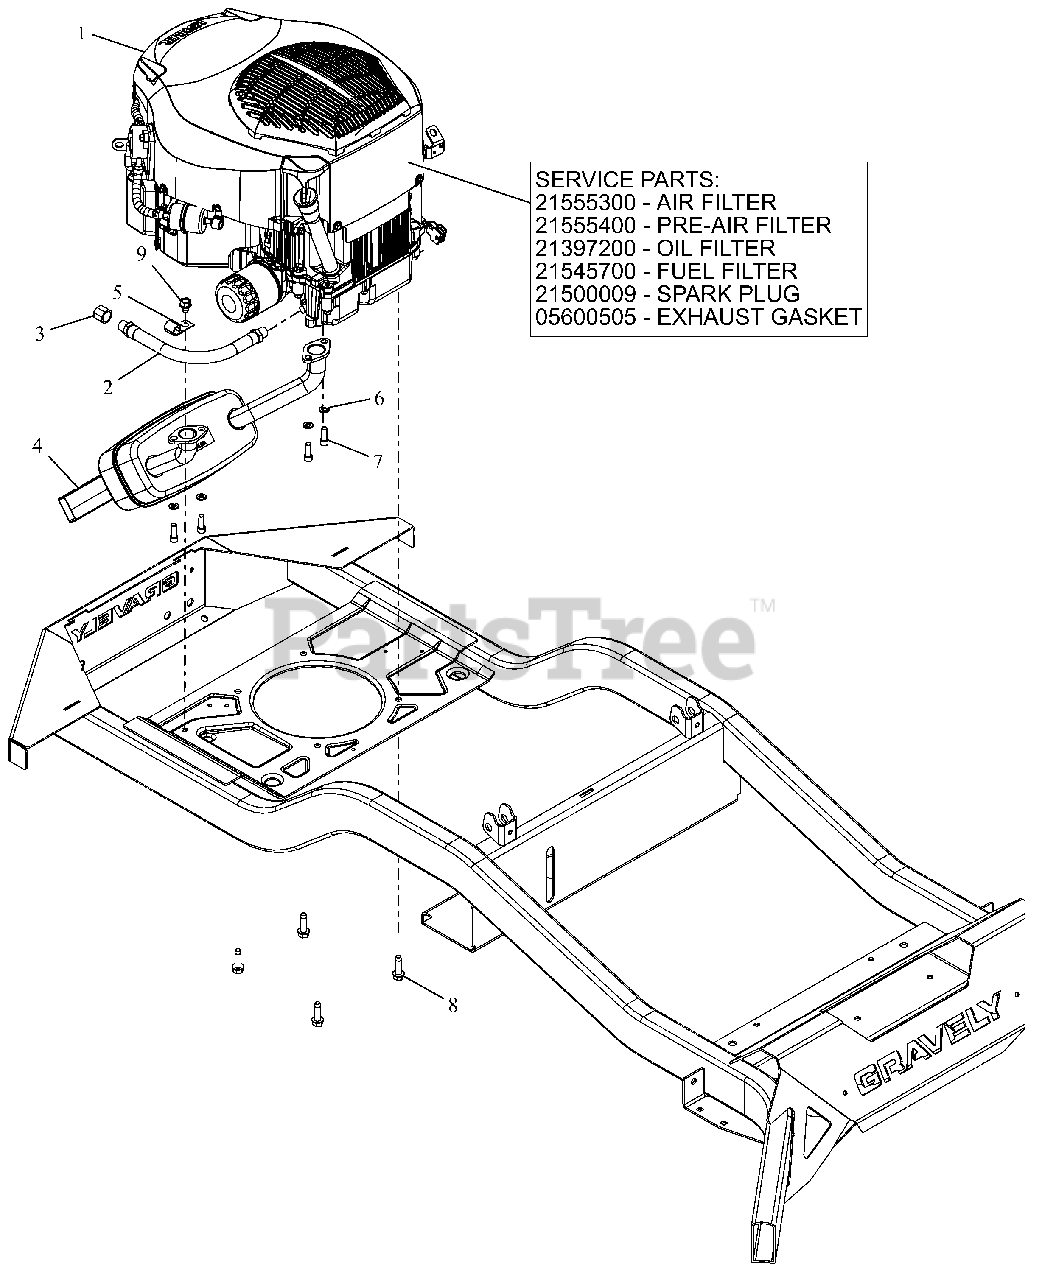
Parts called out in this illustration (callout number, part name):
1	ENGINE, KOHLER - KT745
1	AIR FILTER, KOHLER
1	PRE CLEANER, KOHLER
1	FILTER, OIL - KOH CV20
1	FILTER-FUEL KOHLER COURAGE PRO
1	PLUG, SPARK KOHLER
1	GASKET, MUFFLER KOHLER TWIN
2	HOSE,HYD .38-11-0K M6NO-M6N0
3	PIPE CAP 3/8 NPT FEMALE
4	MUFFLER, KOHLER
6	@WSHR-LK .31X.078 REG YWZC
7	SCR, SKH .312-18X.875 GR8 ZCC
8	@SCR-TAP .38-16X1.25 HWH TR YZ
9	@SCR-TAP .38-16X.50 HWH TR YWZ
